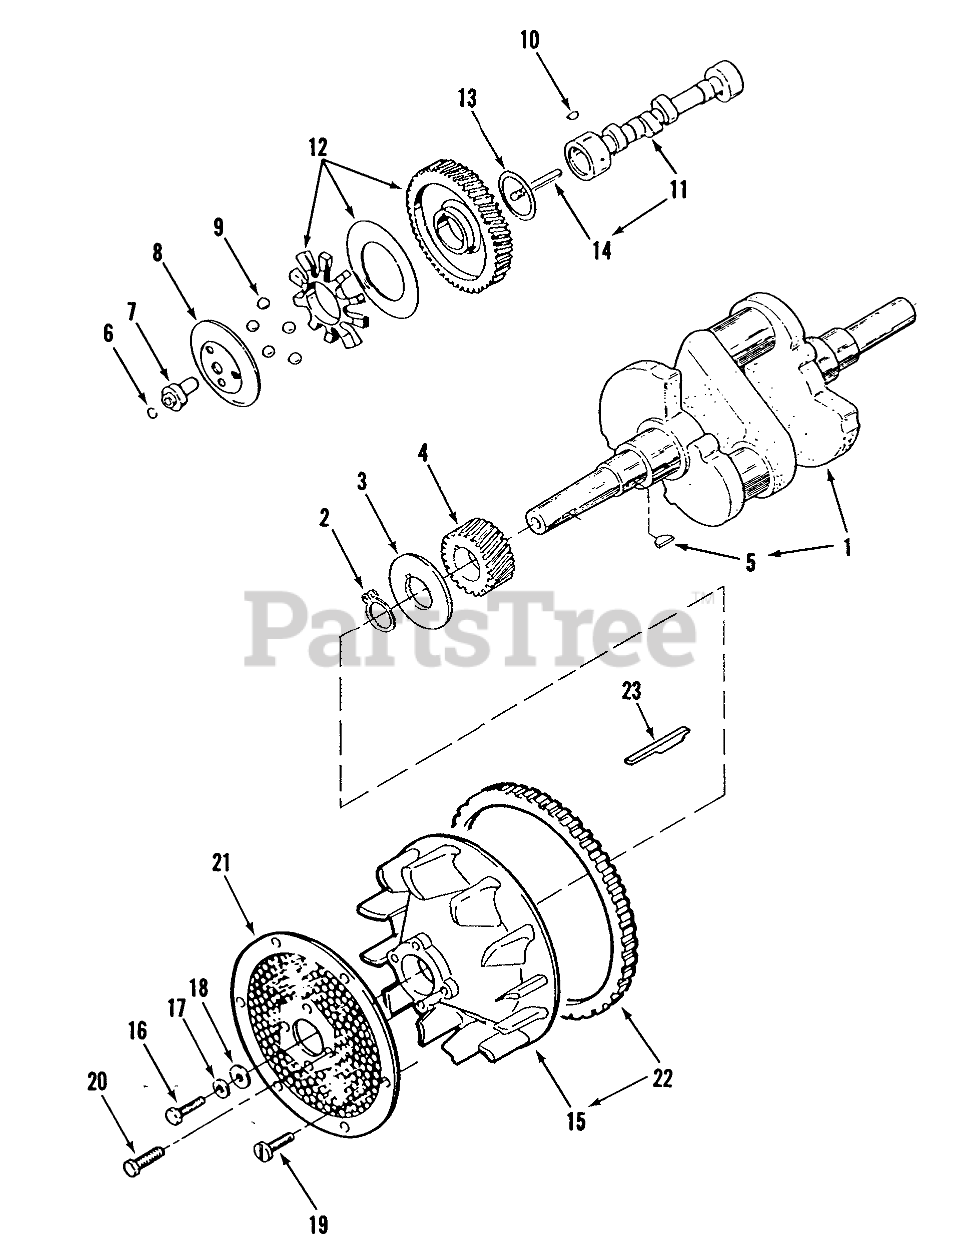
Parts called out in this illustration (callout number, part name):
1	TANK - FUEL
2	Ring Retaining
3	Washer, Gear Retaining
4	DECAL DIAGNOSTICS, FRENCH
5	Key Crankshaft Gear
6	Ring, Retaining
7	Hub, Governor Cup
8	Cup, Governor
9	Ball, Governor
10	Key Crankshaft Gear
11	Camshaft (Includes item 13)
12	Camshaft Gear (Includes Gear, Spacer and Plate)
13	Washer, Thrust
14	Pin, Center
15	Flywheel (Includes Ring Gear)
16	Screw, Cap-Hex Head
17	Washer, Lock-Spring
18	Washer, Flat
19	Flange Lock Hd. Screw No. 10-24 x 3/8
20	Screw, Cap-Hex Head Locking
21	Air Inlet Screen
22	Gear, Ring
23	Flywheel Key
